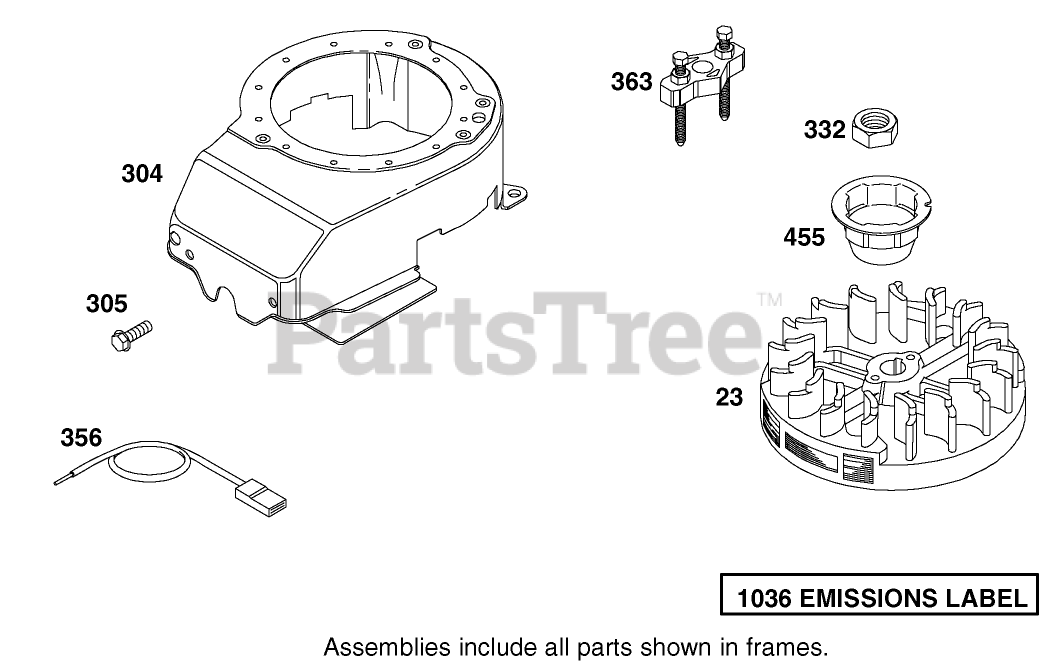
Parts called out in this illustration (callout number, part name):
23	Flywheel
304	Housing-Blower
305	Screw
332	Screw
356	Wire-Stop
363	Puller-Flywheel
455	Cup-Flywheel
1036	Label-Emissions
